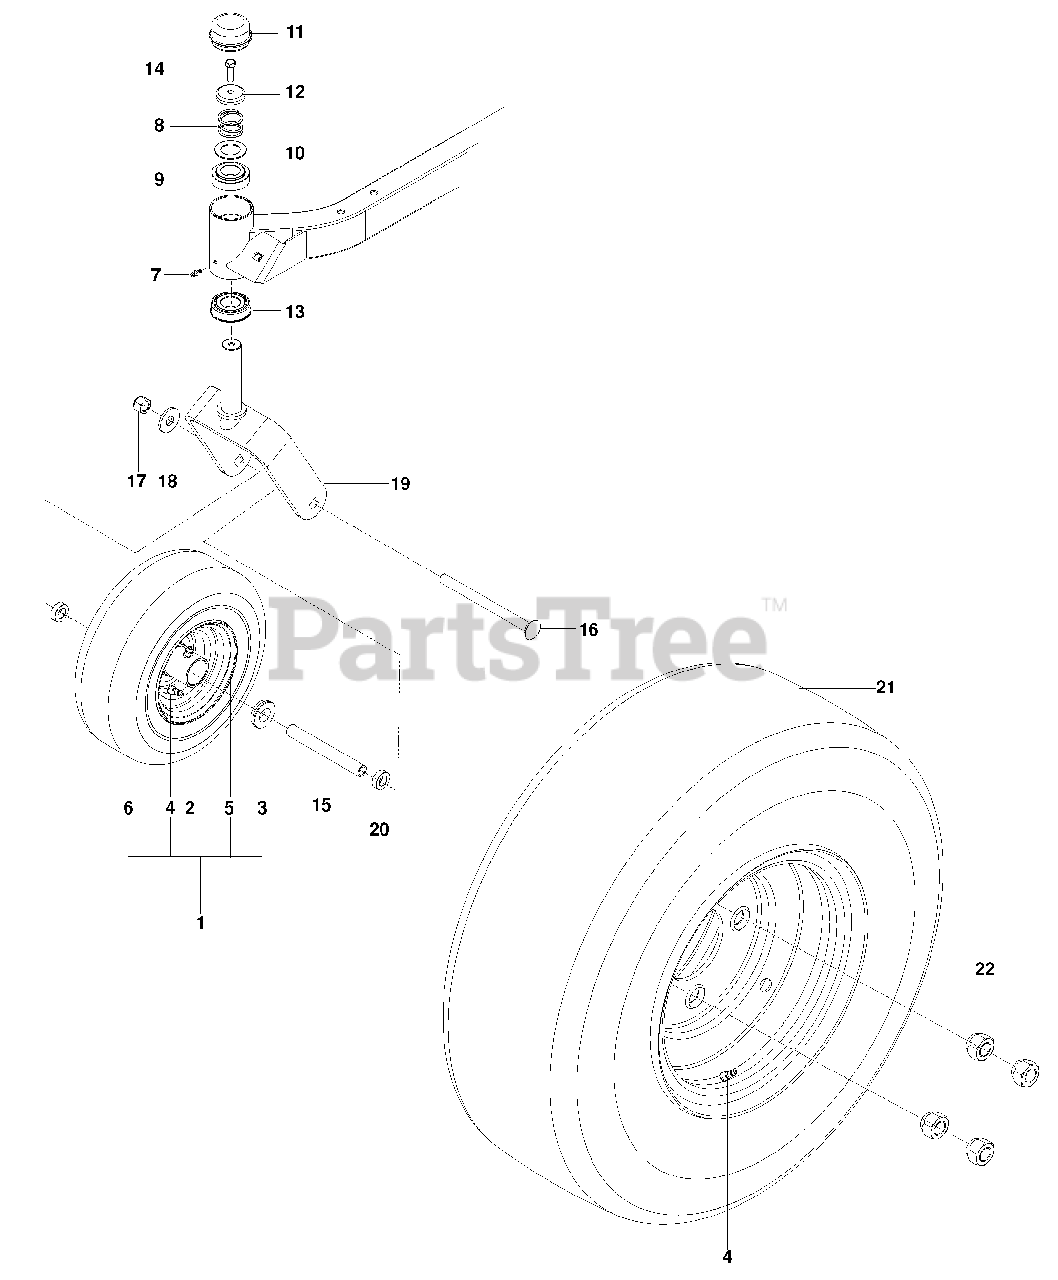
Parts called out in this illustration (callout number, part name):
1	CASTER TIRE ASSY
2	ZERK
3	BEARING, FLANGED
6	TIRE, 410-5 4 PLY
7	ZERK
8	SPRING, CASTER
9	BUSHING, CASTER
11	CAP, GREASE
12	PLUG, CASTER
13	BEARING, FLANGED
14	BOLT, HEX 5/16-18 x 1 NYLOC
16	RHSNB 1/2-13 x 6 1/2
17	NUT 1/2 HEX NYLOC
18	WASHER 1/2 FLAT
19	YOKE, CASTER ORG
20	SPACER 5/16
21	WHEEL ASSY REAR
22	NUT 1/2-20 LUG
